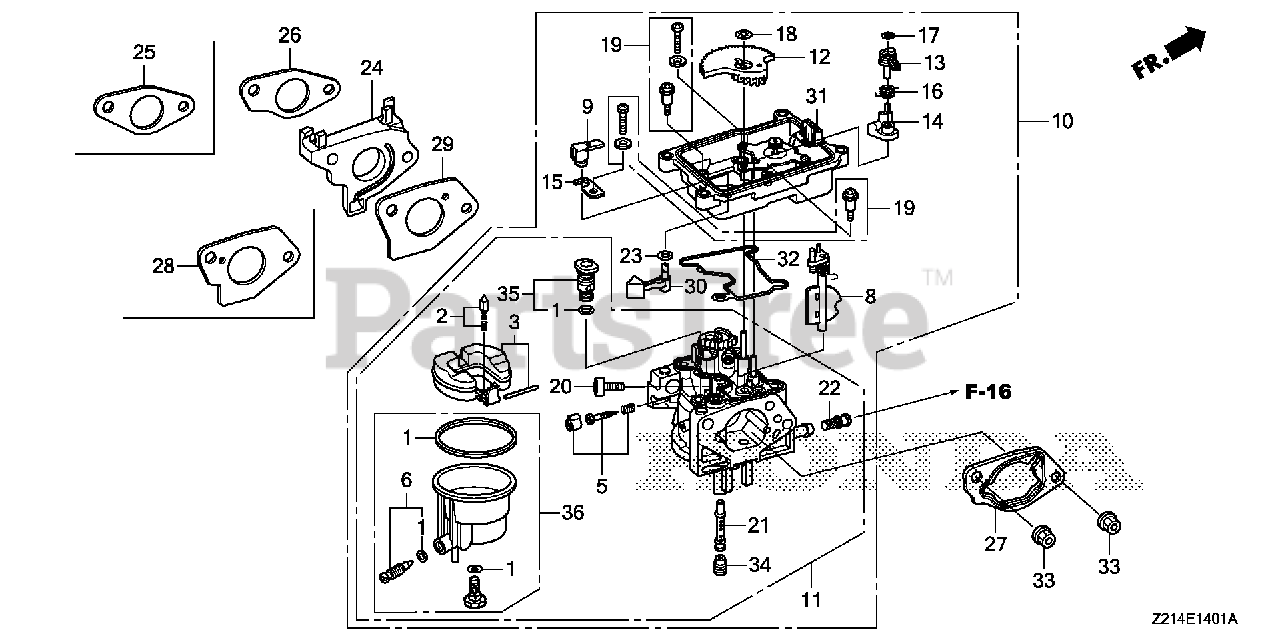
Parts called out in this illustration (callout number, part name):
1	GASKET SET
2	VALVE SET, FLOAT
3	FLOAT SET (CARBURETOR NO.)
5	SCREW SET (Honda Code 4219879). (CARBURETOR NO.)
6	SCREW SET, DRAIN (ADVENTURE GREEN) (CARBURETOR NO.)
9	ARM, MANUAL START
10	CARBURETOR ASSY. (BE96A D)
11	CARBURETOR SET
12	GEAR, MIDDLE
13	ARM, CHOKE
14	LEVER, CHOKE CONTROL
16	SPRING, TORSION COIL
17	CLIP, SPECIAL
18	CLIP, SPECIAL
20	SCREW, STOP
21	NOZZLE, MAIN
22	SCREEN, FUEL STRAINER
23	O-RING (CARBURETOR NO.)
24	INSULATOR, CARBURETOR
26	GASKET, CARBURETOR INSULATOR
27	SPACER, CARBURETOR
29	GASKET, CARBURETOR
30	LEVER, MANUAL START
31	CASE, MOTOR
33	NUT, FLANGE (6MM)
34	JET, MAIN (#105) Use from Engine SN BE87H A.
34	JET, MAIN (#108) (CARBURETOR NO.)
34	JET, MAIN (#112)
35	JET SET, PILOT (#45) (CARBURETOR NO.)
36	BOLT KIT, FUEL CHAMBER
